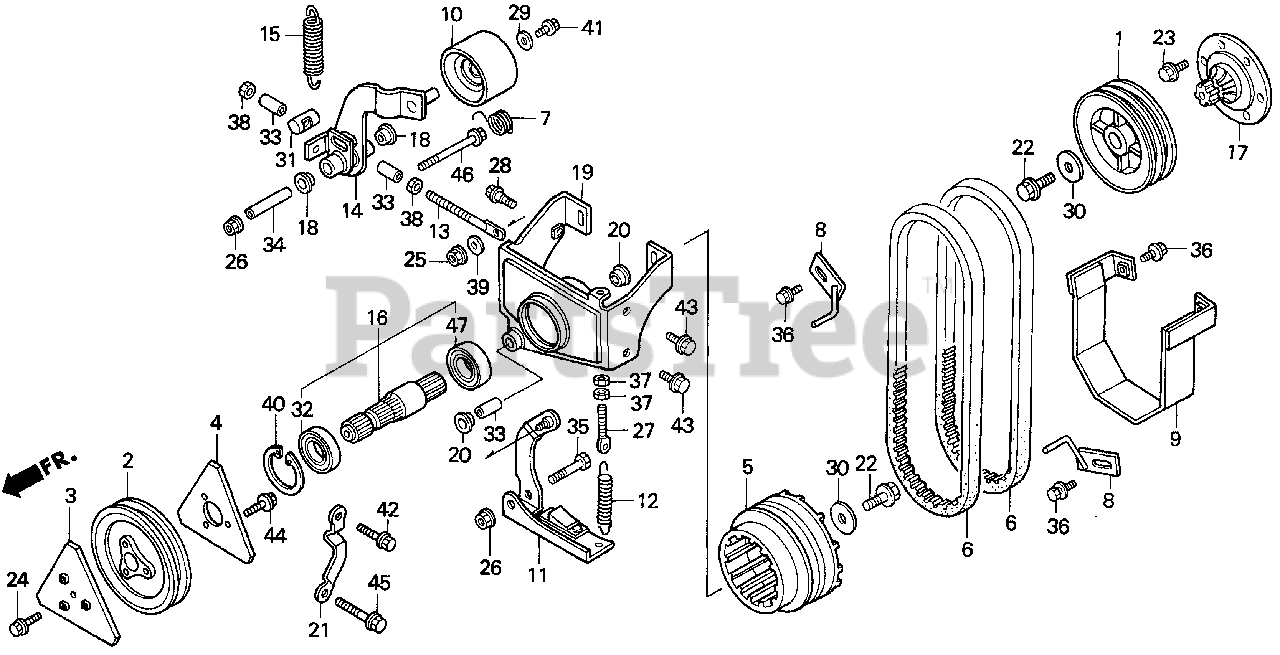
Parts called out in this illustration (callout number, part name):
1	PULLEY, DRIVE (124MM)
2	PULLEY, FR. P.T.O. DRIVE (145MM)
3	PATCH, PULLEY (A)
4	PATCH, PULLEY (B)
5	PULLEY, DRIVEN (119MM)
6	V-BELT (SB-35)
7	SPRING, TENSIONER RETURN
8	STOPPER A, BELT
9	STOPPER B, BELT
10	ROLLER, TENSION
11	BRAKE, FR. P.T.O.
12	SPRING, P.T.O. BRAKE
13	ROD, FR. P.T.O. BRAKE ARM
14	ARM, TENSIONER
15	SPRING, BELT TENSION
16	SHAFT, FR. P.T.O.
17	SHAFT, FR. P.T.O.
18	BUSH, PARKING BRAKE
19	BRACKET, FR. P.T.O.
20	BUSH, CHANGE ARM
21	STOPPER, V-BELT DRIVEN
22	BOLT, SPECIAL (10X25)
23	BOLT, UBS (8X17)
24	BOLT, FLANGE (8X20)
25	NUT, SELF-LOCK (6MM)
26	NUT, SELF-LOCK (8MM)
27	BOLT, ADJUSTING (6MM)
28	BOLT (8X20)
29	WASHER (6MM)
30	WASHER (10.5X40X4)
31	PIN, CLUTCH LEVER
32	BEARING, RADIAL BALL (28X52X12)
33	COLLAR, FR. P.T.O. BRAKE
34	COLLAR (8X12X64.3)
35	BOLT, HEX. (8X45)
36	BOLT-WASHER (6X16)
37	NUT, HEX. (6MM)
38	NUT, HEX. (8MM)
39	WASHER, PLAIN (6MM)
40	CIRCLIP (INNER) (52MM)
41	BOLT, FLANGE (6X16)
42	BOLT, FLANGE (8X16)
43	BOLT, FLANGE (8X20)
44	BOLT, FLANGE (8X38)
45	BOLT, FLANGE (10X20)
46	BOLT, FLANGE (8X85)
47	BEARING, RADIAL BALL (6205UU)
